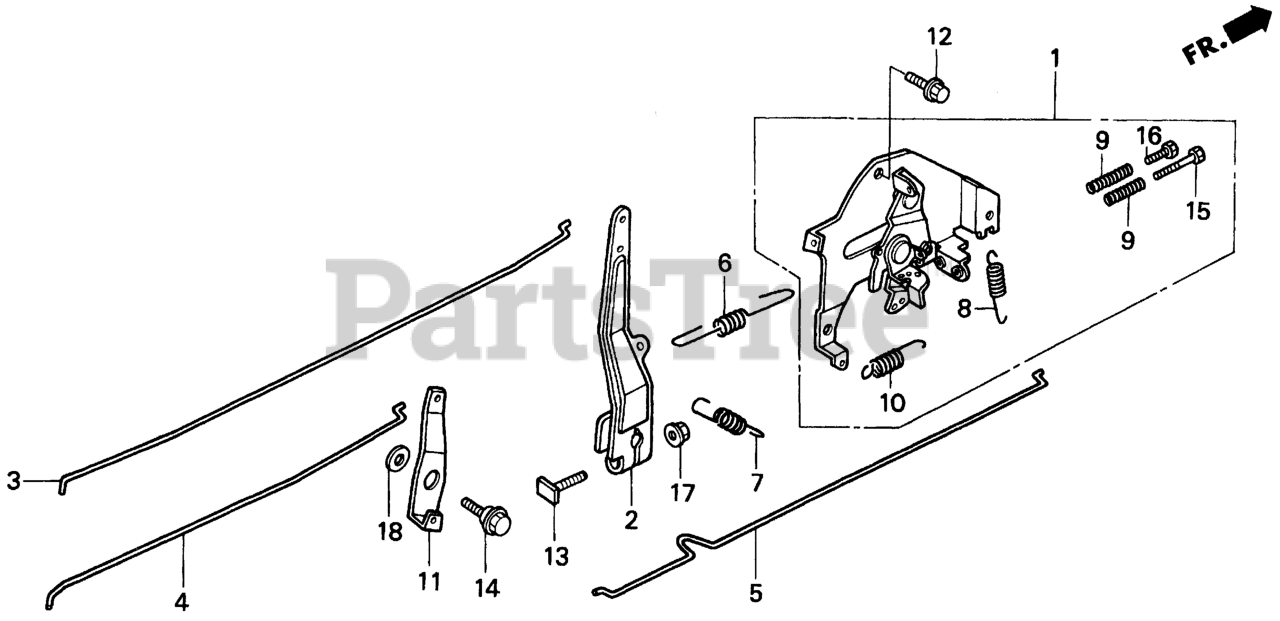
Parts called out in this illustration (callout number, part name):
1	CONTROL ASSY.
2	ARM, GOVERNOR
3	ROD, GOVERNOR
4	ROD, CHOKE
5	ROD, JOINT
6	SPRING, GOVERNOR
7	SPRING, GOVERNOR PRIMARY
8	SPRING, LEVER
9	SPRING, CONTROL ADJUSTING Use from Engine SN 2327377.
10	SPRING, CABLE RETURN
11	LEVER, CHOKE JOINT
12	BOLT, FLANGE (6X12) (CT200)
13	BOLT, GOVERNOR ARM
14	BOLT, FLANGE (6MM)
15	BOLT, RECESSED (5X34)
16	BOLT, HEX. (5X20)
17	NUT, FLANGE (6MM)
18	WASHER, PLAIN (6MM)
